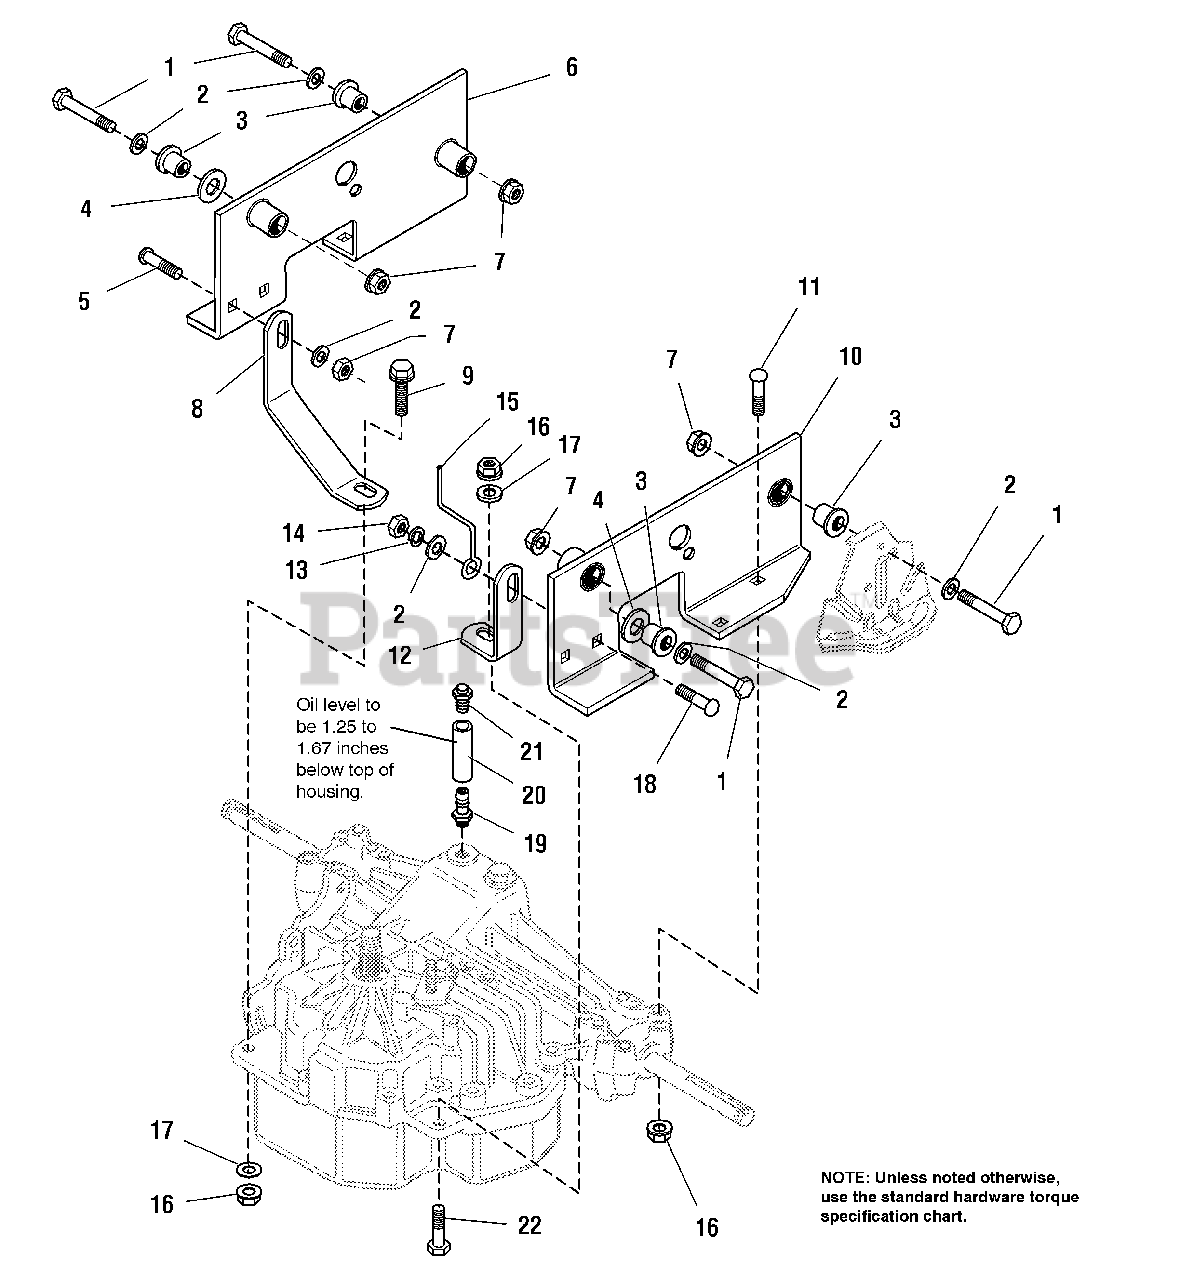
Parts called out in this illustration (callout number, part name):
1	CAPSCREW, Hex H.D., 3/8-16 x 2
2	WASHER, Plain, 3/8
4	WASHER, Plain, 1 x 1-3/4
5	CARRIAGE BOLT, 3/8-16 x 1
6	SUPPORT, Trans. Asst. R.H.
7	NUT, Hex Flange, small, 2-way lock, 3/8-16
8	TORQUE STRAP, R.H.
9	SCREW, Hex Whizlock, 5/16-18 x 2-1/4
10	SUPPORT, Trans. Asst. L.H.
11	CARRIAGE BOLT, 5/16-18 x 2-3/4
12	TORQUE STRAP, L.H.
13	LOCKWASHER, 3/8
14	NUT, Hex, 3/8-16
16	NUT, Hex Flange, Small, 2-way lock, 5/16-18
17	WASHER, 5/16
18	CARRIAGE BOLT, 3/8-16 X 1-1/4
19	FITTING, Vent
22	CAPSCREW, Hex H.D. 5/16-18 x 1-1/2
